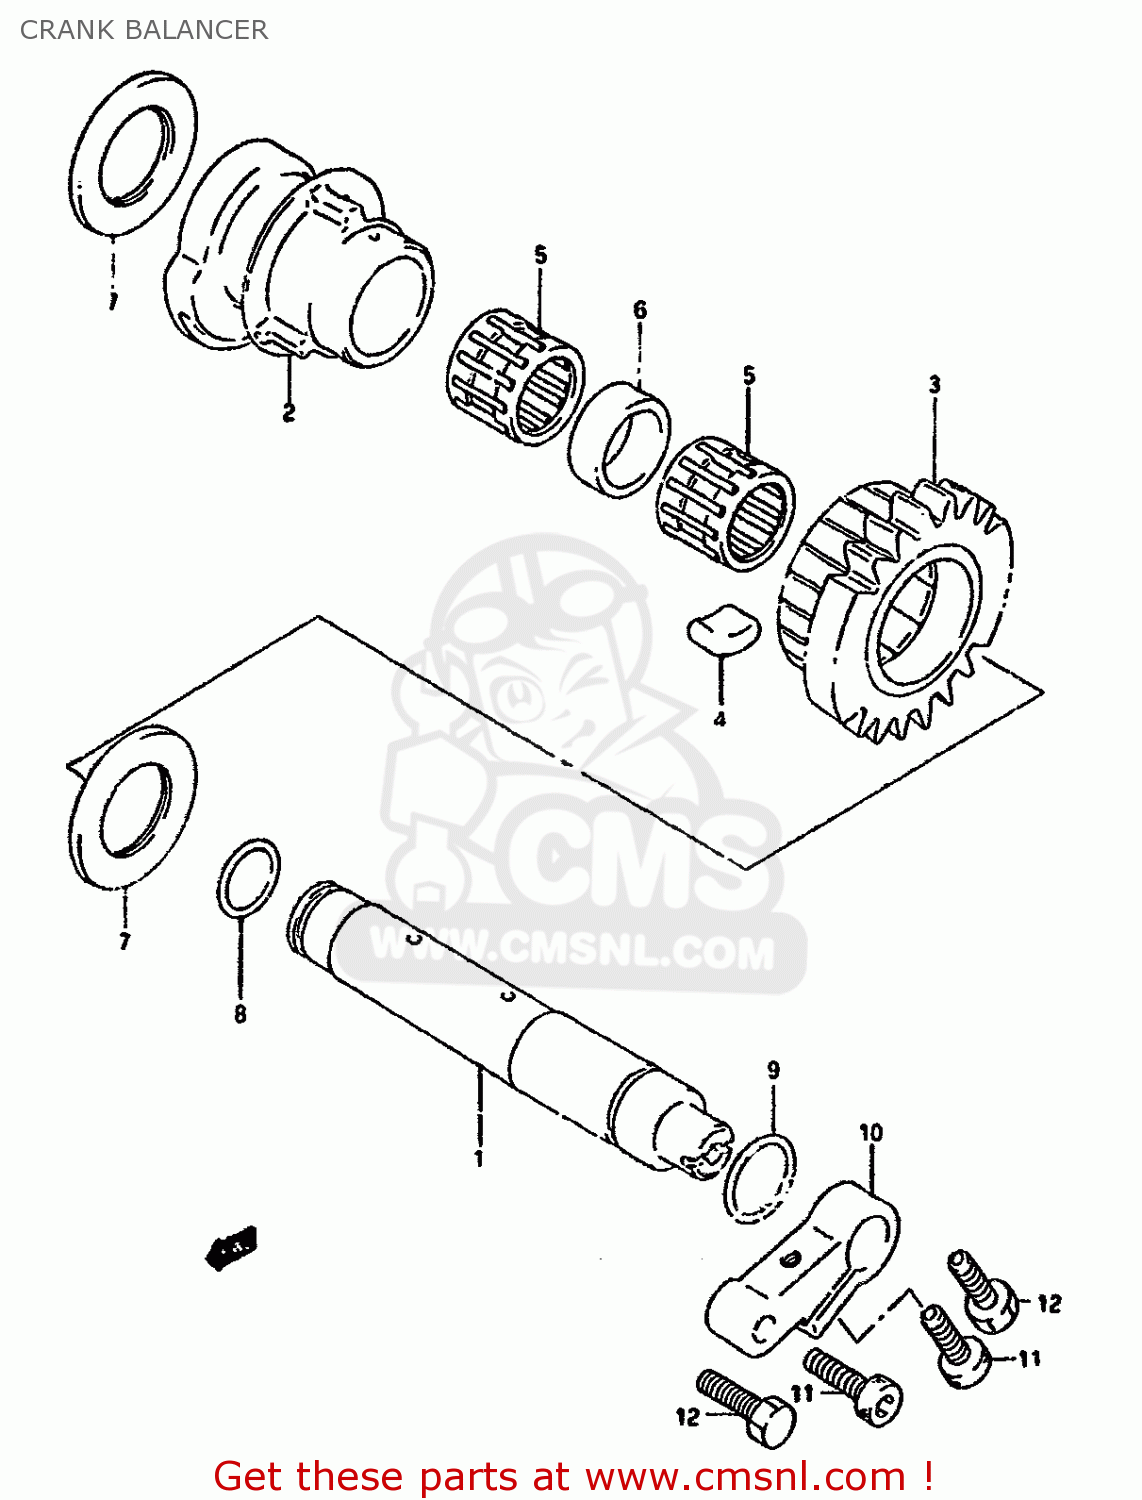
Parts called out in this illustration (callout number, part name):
1	SHAFT COMP,BALANCER
2	BALANCER,CRANKSHAFT
3	GEAR,CRANK BALANCER
4	DAMPER,BALANCER GEAR
5	BEARING 19X25X22.8
6	SPACER (19X25X10)
7	WASHER (22X40X1)
8	O RING(D:1.9,ID:14.5)
9	O RING(D:1.9,ID:16.6)
10	ARM,BALANCER SHAFT
11	BOLT
12	BOLT
